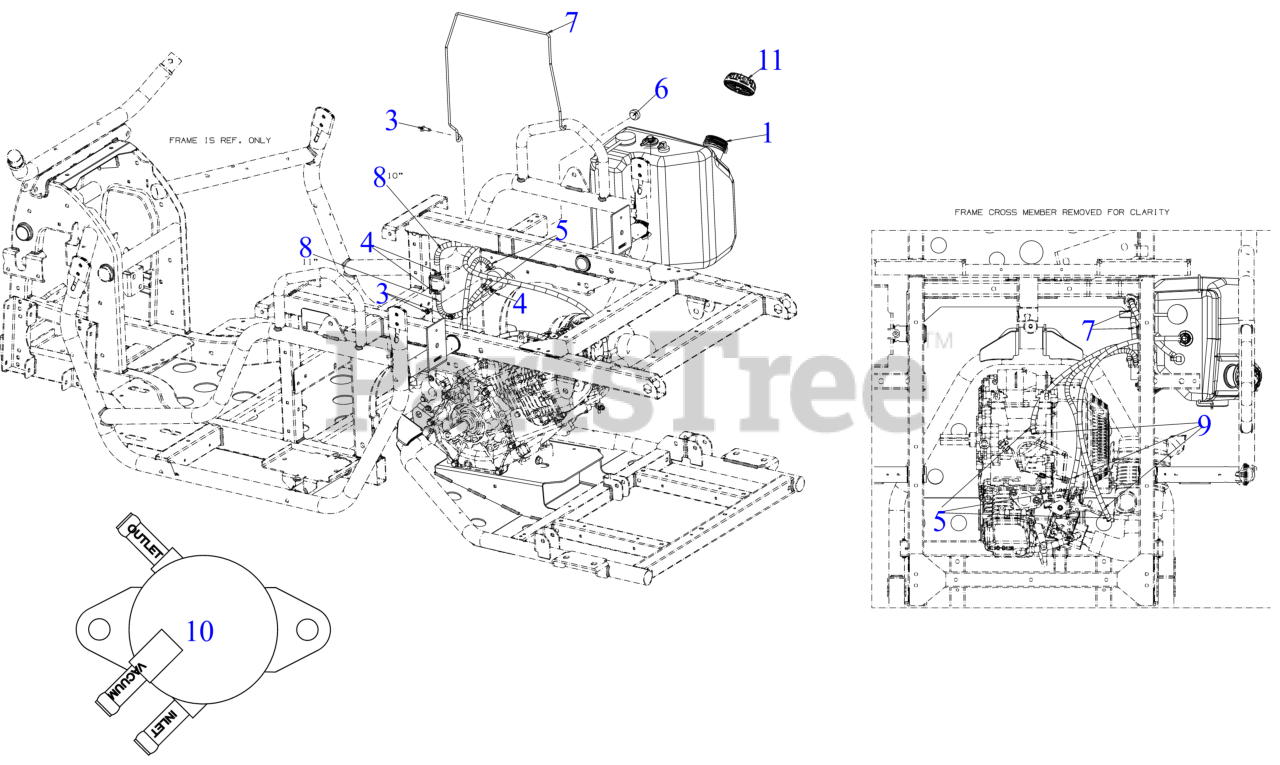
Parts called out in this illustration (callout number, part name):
1	FUEL TANK (3.9GAL)
3	SCREW 1/4-20 x .750
4	HOSE CLAMP 1/20
5	HOSE CLAMP 0.470
6	RUBBER BUMPER 1.000 x .313
7	FUEL TANK RETENTION ROD
8	FUEL HOSE LOW PERMEATION 22"
9	FUEL HOSE LO PERMEATION 62"
10	ENGINE FUEL PUMP
11	FUEL CAP W/TETHER VENTED
